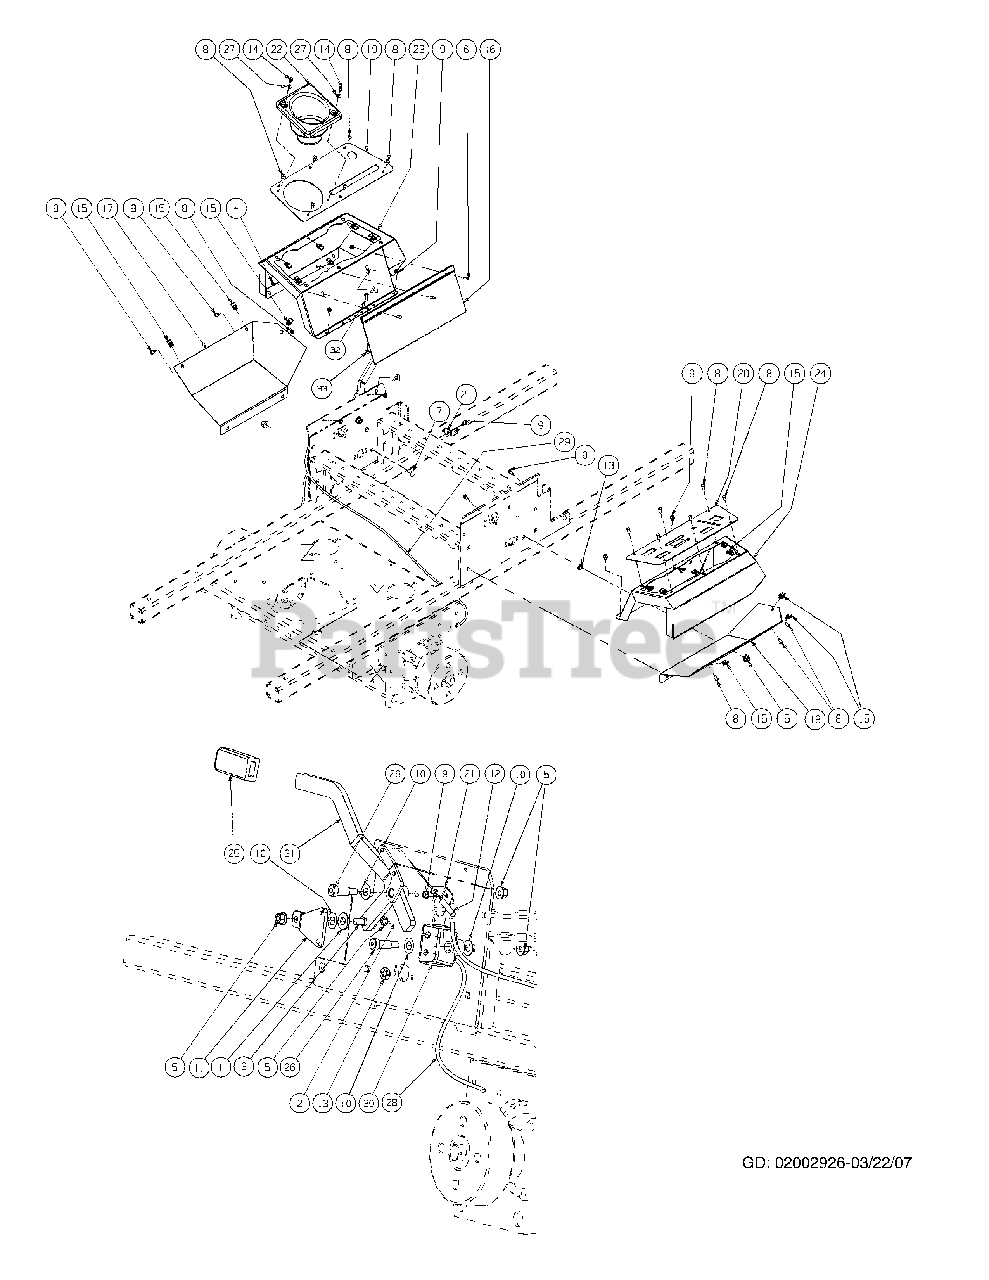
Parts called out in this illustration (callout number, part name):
1	Washer, 1/2 Zinc
2	Carriage Bolt, 3/8-16, 1.00
3	Shoulder Bolt, 1/2 x 1/2
4	Lock Nut, Nylon Insert, 10-32
5	Flange Lock Hex Nut, 3/8-16
6	Phillips Head Machine Screw, 10-32 x 5/8
7	Carriage Bolt, 3/8-16 x .75
8	Screw Button Head, 1/4-20 x .5
9	Screw, TT, 1/4-20, 0.5, Hex Index Washer
10	Washer, .508 ID x 1.0 OD x .020
11	Centering Bracket
12	Left Hand Brake Cable
13	Push Retainer, 3/8
14	Screw, #10-32 x 0.500
15	U-Nut, 1/4-20
16	Bag, Debris Storage
17	Lower Panel, LH
18	Lower Panel, RH
19	Control Panel Cover, LH
20	Control Panel Cover, RH
21	Brake Cable Mounting Bracket
22	Cup Holder
23	Control Panel, LH
24	Control Panel, RH
25	Parking Brake Grip
26	Shoulder Bolt, 1/2 x 1.00, 3/8-16
27	Washer, 3/16
28	Brake Cable, LH
29	Brake Cable, RH
30	Brake Cable Bracket
31	Brake Lever
32	Screw, Hex, Cap, 1/4-20 x .75
33	Lock Nut, 1/4-20
